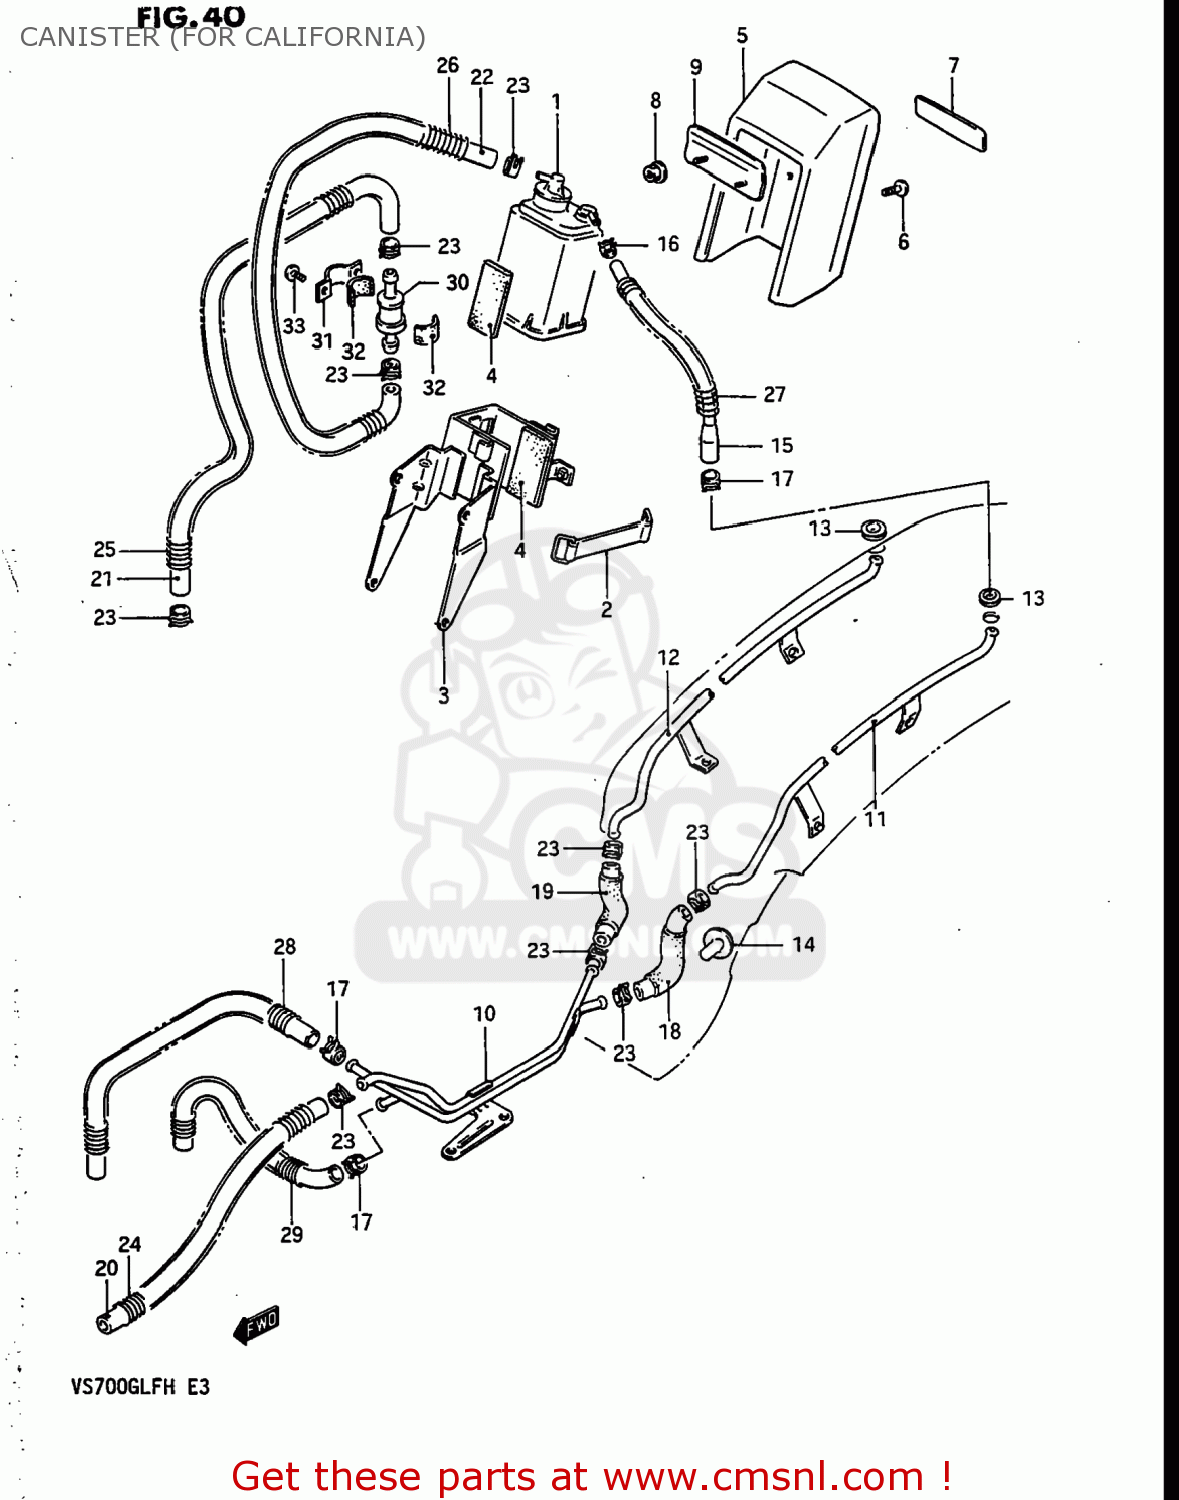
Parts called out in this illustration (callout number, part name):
1	CANISTER ASSY,CHARCOAL
2	BAND
3	BRACKET,CANISTER
4	CUSHION
5	COVER,CANISTER
6	SCREW (5X10)
7	EMBLEM,TOOL HOLDER,REAR
8	NUT
9	PLATE,CANISTER
10	PIPE,CSTR JOINT FR
11	PIPE
12	(CA) PIPE,CANISTER JOINT REAR
13	GROMMET
14	GROMMET
15	HOSE
16	CLAMP
17	CLIP
18	(CA) HOSE NO.6
19	(CA) HOSE NO.2
20	HOSE
21	HOSE
22	HOSE
23	(CA) CLIP
24	SPRING
25	(CA) SPRING
26	SPRING
27	SPRING
28	SPRING
29	SPRING
30	VALVE,FUEL TANK BREATHER
31	PLATE,FUEL TANK BREATHER NO.2
32	CUSHION
33	SCREW
